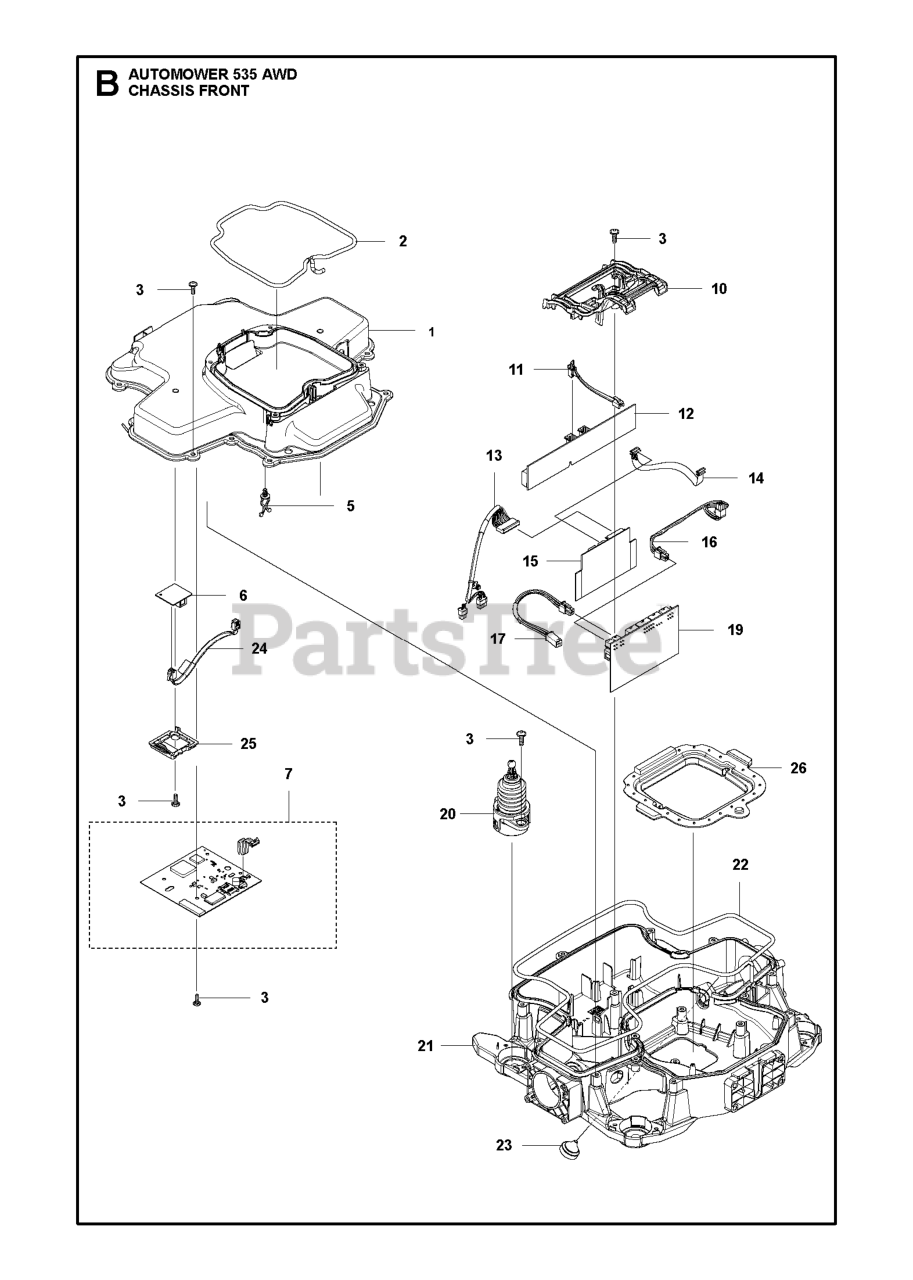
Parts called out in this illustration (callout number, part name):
3	SCREW 14MM
5	HOLDER TWIST LOCK
15	PRINTED CIRCUIT ASSY ULTRASONI
23	GROMMET M16
